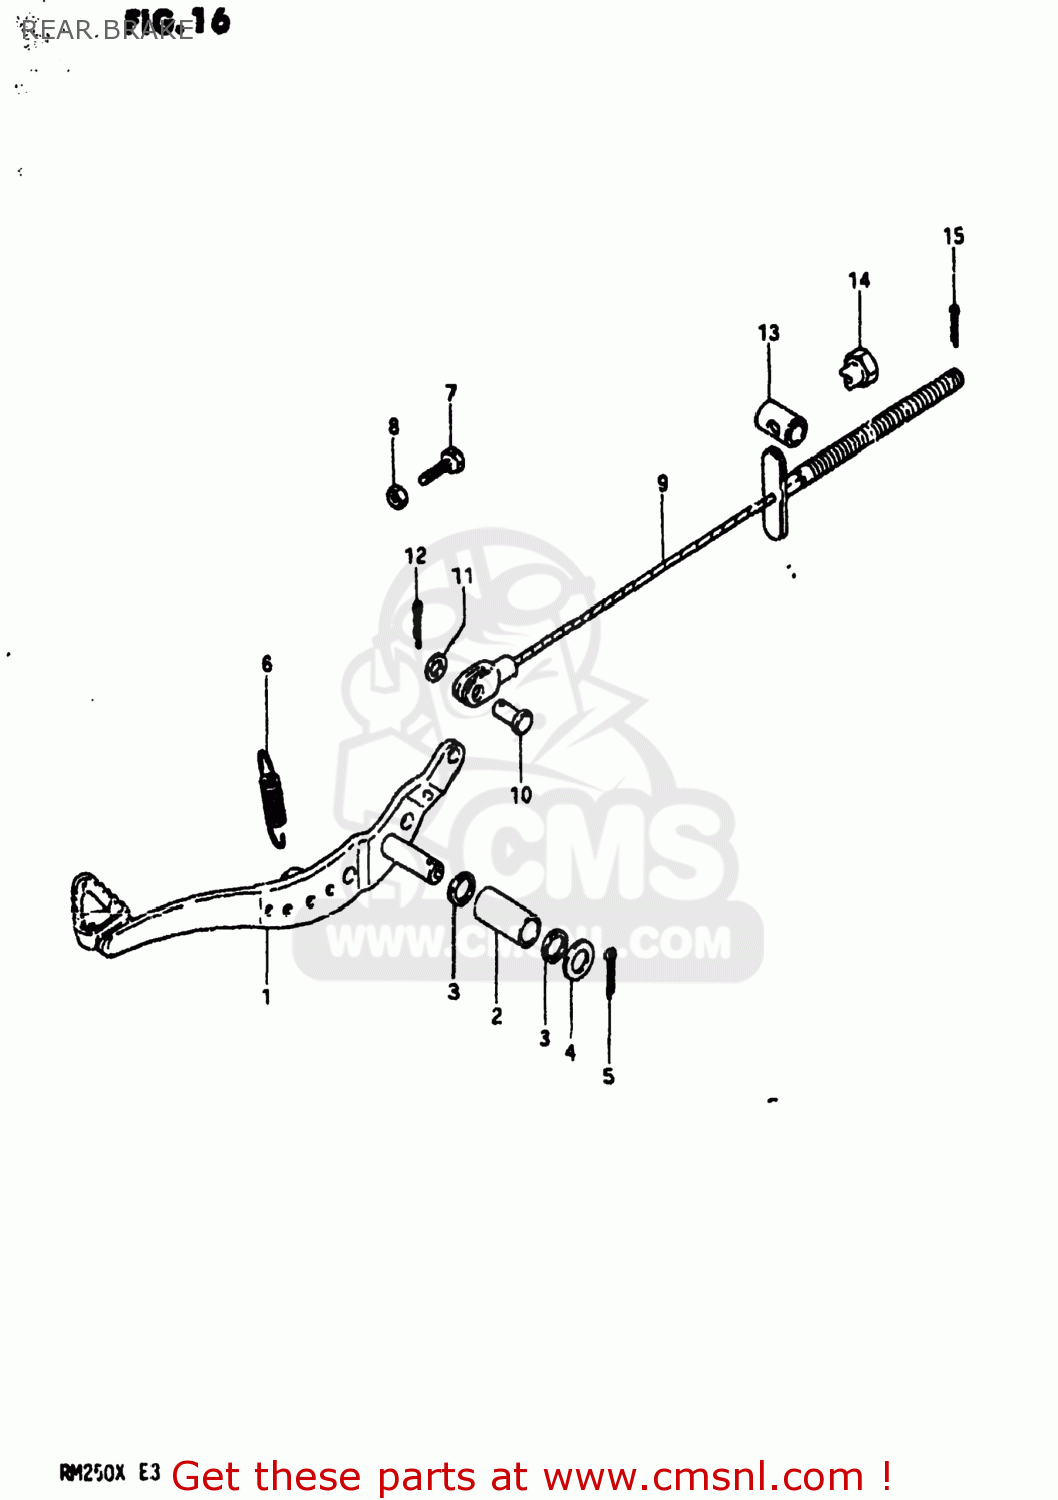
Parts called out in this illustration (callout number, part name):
1	PEDAL,BRAKE
2	BUSHING
3	O RING(D:2.2,ID:11.8)
4	WASHER
5	PIN 30X20
6	SPRING
7	BOLT(6X23)
8	NUT
9	CABLE ASSEMBLY,REAR BRAKE
10	PIN(L:17.5)
11	WASHER
12	PIN 20X20
13	PIN
14	NUT
15	PIN
